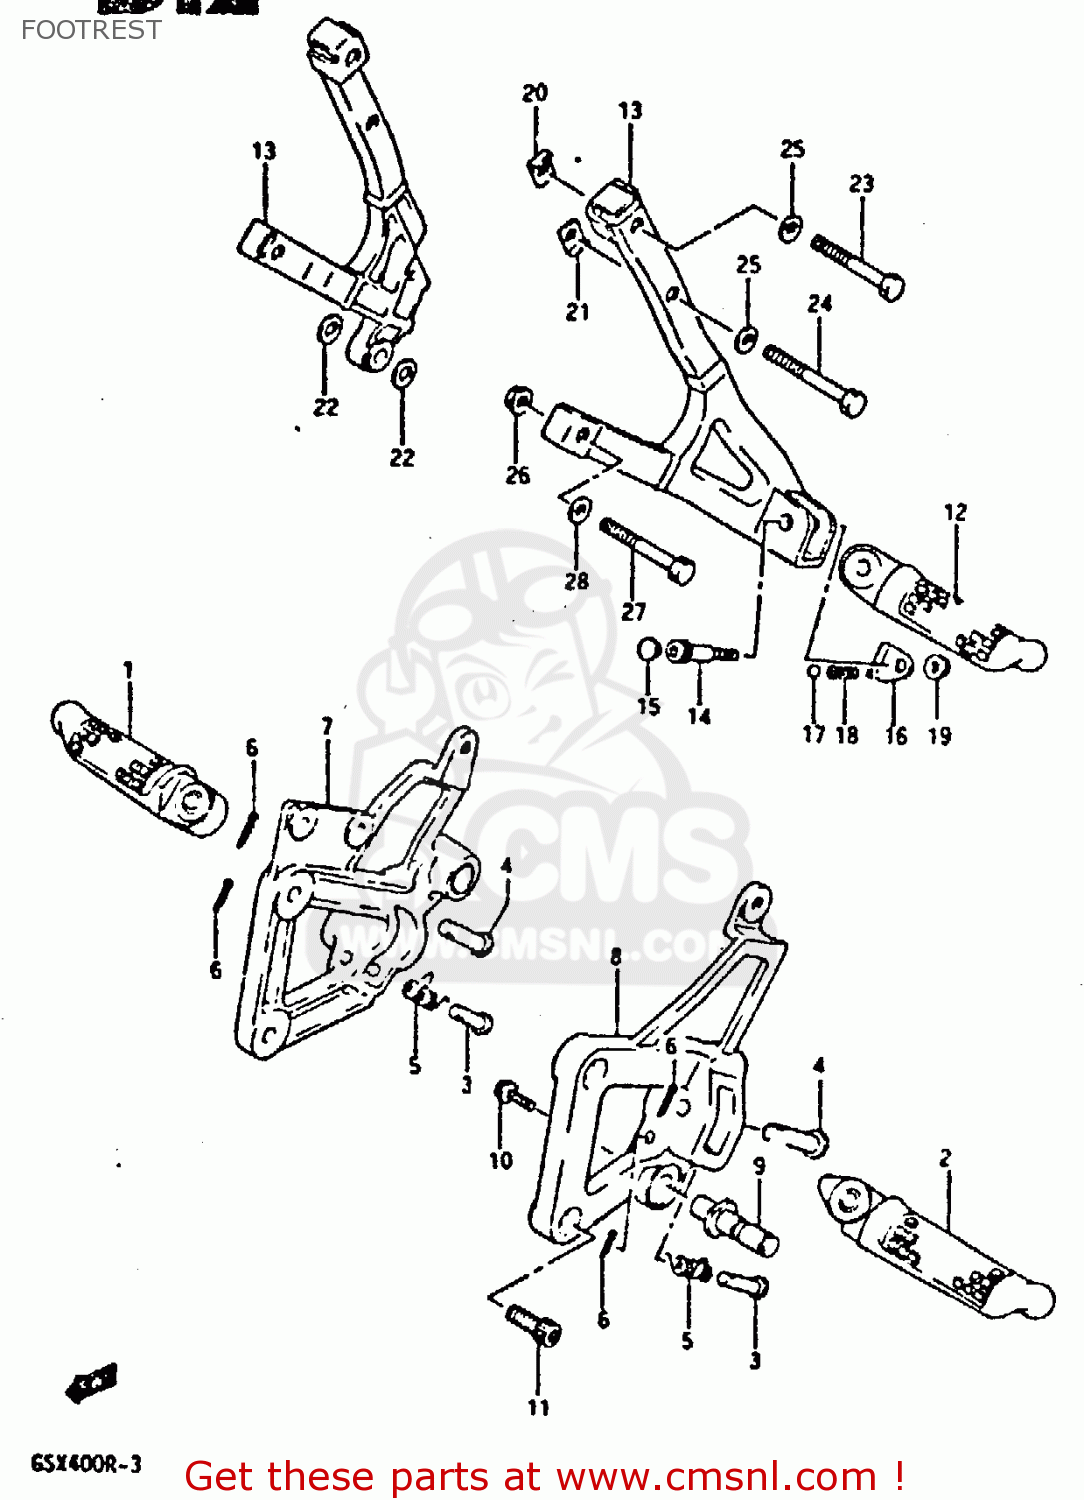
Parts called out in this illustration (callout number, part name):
1	FOOTREST,FR.LH
2	FOOTREST ASSY,FRONT
3	PIN
4	PIN
6	PIN
7	BEUGEL.VOETSTEU
8	BRACKET.FOOTRES
9	BOSS,GEAR SHIFT
10	BOLT 6X16
11	BOLT
12	FOOTREST ASSY
14	BOLT,PILLION FOOTREST
15	CAP(OD:10)
16	PLATE,SPRING STOP,R
17	BALL
18	SPRING
19	NUT
22	WASHER
23	BOLT 8X55
24	BOLT 8X45
25	WASHER
26	NUT, WHEEL SET
27	BOLT 8X50
28	WASHER
